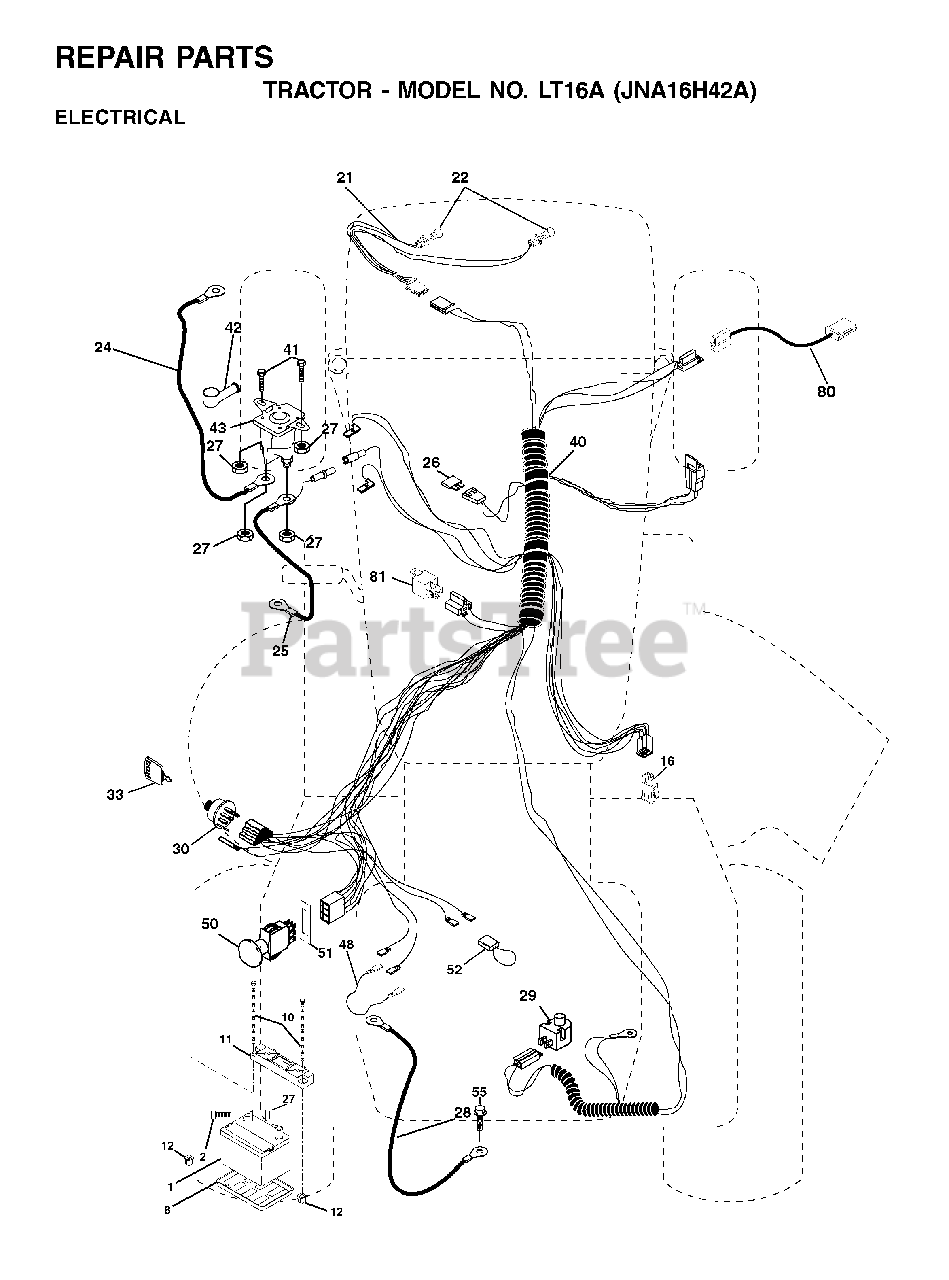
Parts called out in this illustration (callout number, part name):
1	BATTERY 12 VOLT 25 AMP
8	BATTERY TRAY T
10	BOLT 1/4-20 X 7.5
11	BATTERY HOLDDOWN
12	NUT, PUSH NYLON 1/4" BATTERY
16	SWITCH INTERLOCK
22	LIGHTBULB
24	BATTERY CABLE GT
25	CABLE BATTERY 6 GA 22" W/16W
26	FUSE 20AMP
27	NUT
28	CABLE GROUND 6 GA 21" 90T BLK
29	PLUNGER SWITCH (COLOR:OLIVE)
30	IGNITION SWITCH
33	KEY MLD GEN DELTA
42	TERMINAL COVER
43	SOLENOID
50	PTO SWITCH
51	RETAINING RING
52	WIRE PROTECTION LOOP
80	HARNESS, CLUTCH
81	RELAY.ASSY.T
